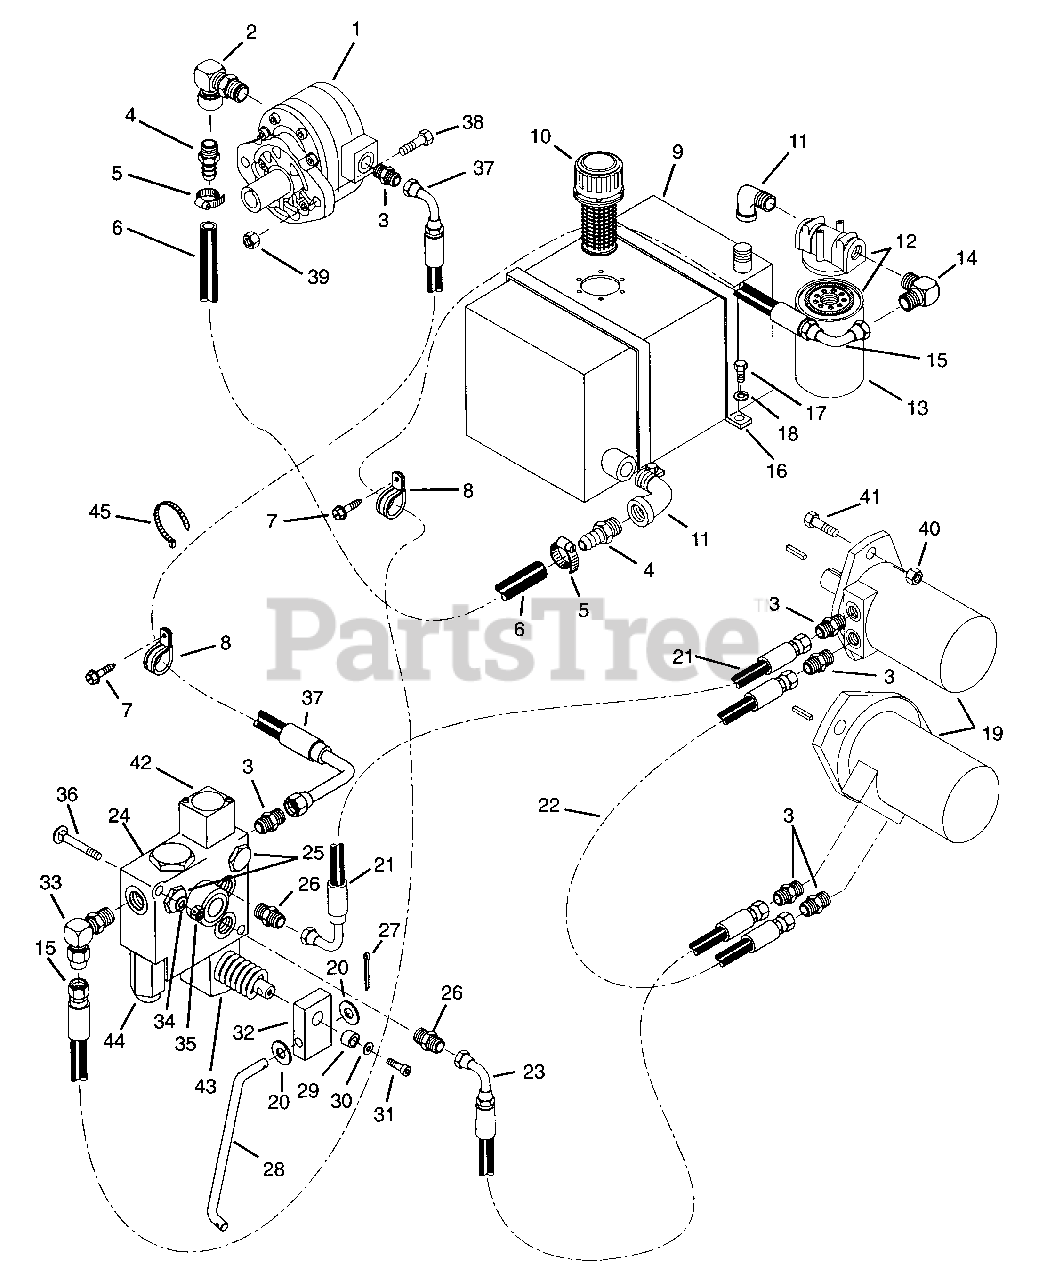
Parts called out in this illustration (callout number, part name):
1	Pump-Hydraulic
2	Elbow-Female
3	Adapter-Hydraulic-Steel 7/8 "O" To 3/4
4	Barbed Insert Adapter
5	Clamp-Hose H-20 1-3/16 To 1-3/4
6	Hose-Suction (18 IN.)
7	Screw-Tapping .38-16 X .50 HWH
8	Clamp-Steel
9	Hydraulic Oil Tank
10	Filler Cap Assembly
11	Street Elbow 90 Degree Galvanized 3/4 IN.
12	Filter
13	Replacement Element (Part of Filter)
14	Hydraulic Fitting
15	Hose-Hydraulic 64 IN. ST
16	Hydraulic Tank Straps
17	Bolt-Hex .38-16 x .75 Grade 5
18	Washer-Locking .38 x .094
19	Motor-Hydraulic
20	Washer-Flat-Steel .406 x .812 x .065
21	Hose-Hydraulic 22 IN. w/elbow
22	Hose-Hydraulic-Steel
23	Hose-Hydraulic 26.5 IN. w/elbow
24	Valve-Direction/Flow Control
25	Plug-Hex 3/4-16 "O" Ring
26	Adapter-hydraulic-Steel 3/4 "O" To 3/4
27	Pin-Cotter .12 x .75
28	Rod-Valve
29	Spacer .318 x .430 x .375
30	Washer-Flat-Steel .38 x .875 x .083
31	Screw-Socket Head M8 x 1.25 x 20
32	Adapter-Valve Handle
33	Adapter-Hydraulic Elbow 7/8 "O" To 3/4
34	Washer-Locking .31-.078
35	Nut-Locking-Center .31-18
36	Bolt-Round Head Square Neck .31-18 x 2.75
37	Hose-Hydraulic 70 IN. w/Elbow
38	Bolt-Hex .44-14 X 1.50 Grade 5
39	Nut-Locking-Center .44-14
40	Nut-Locking-Center .50-13
41	Bolt-Hex .50-13 X 1.50 Grade 5
42	Detent Assembly-Control Valve
43	Lever Assembly-Hydraulic Control Valve
44	Relief Valve-Hydraulic Control Assembly
45	Tie Wrap
